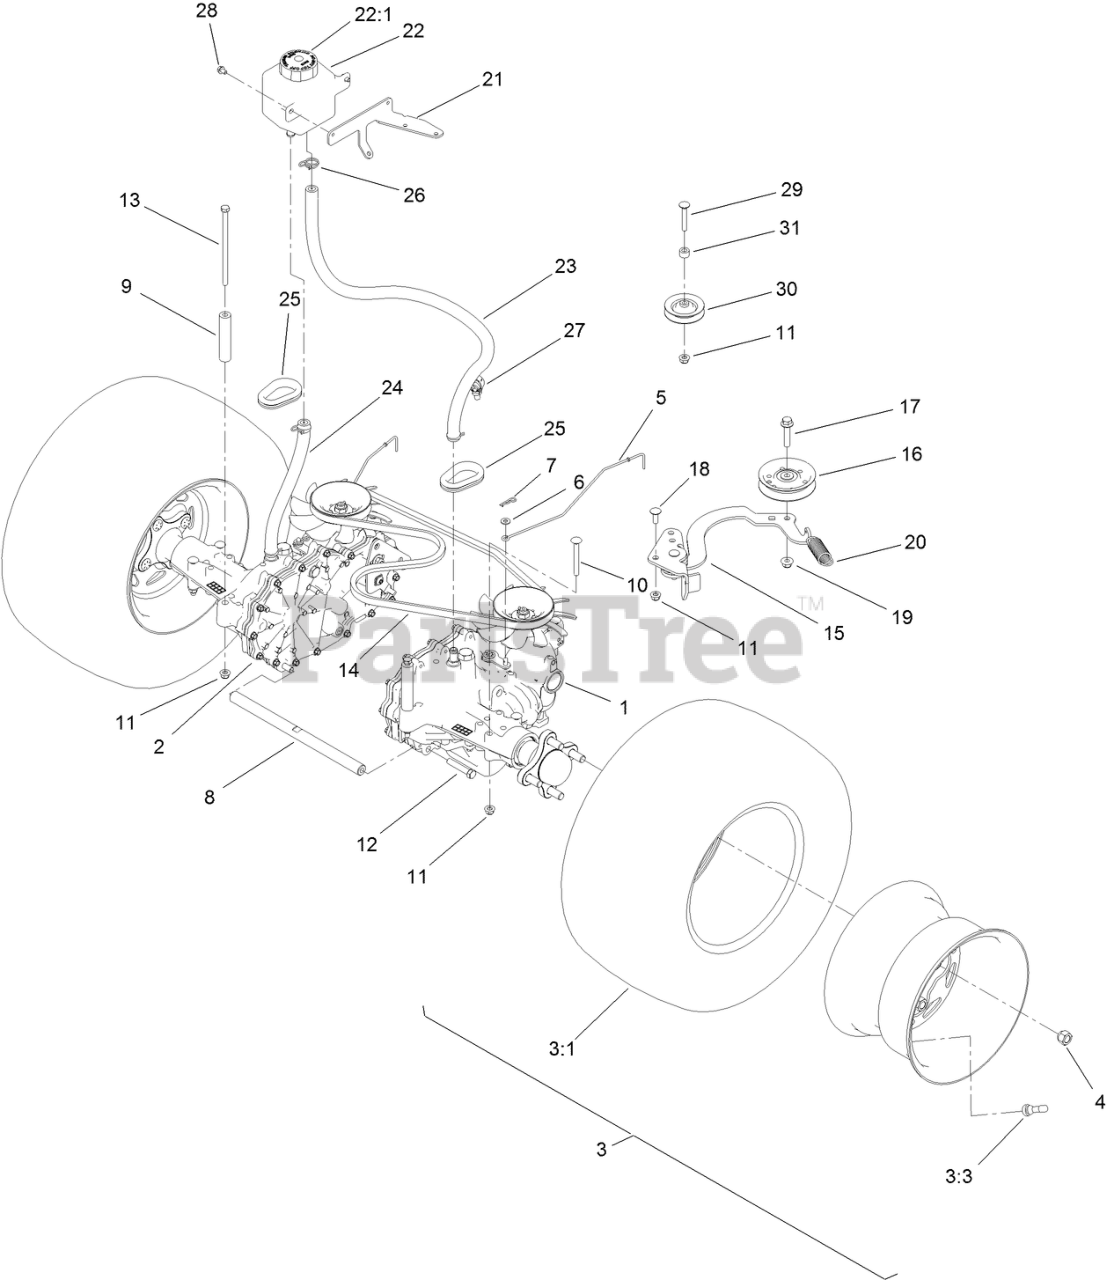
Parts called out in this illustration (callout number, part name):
1	TRANSMISSION, ZT-2800 LH
2	TRANSMISSION, ZT-2800 RH
3	TIRE ASM
4	NUT-LUG
5	ROD-BYPASS
6	WASHER-FLAT
7	PIN-COTTER
8	SHAFT-CROSS, HYDRO
9	SPACER - TRANSMISSION
10	SCREW-CARR
11	NUT-HF, NI
12	SCREW-HH W/LOCTITE
13	SCREW-HH
14	BELT-V
15	IDLER ARM ASM
16	PULLEY-IDLER, FLAT
17	SCREW-HHF
18	BOLT-CARR
19	NUT-HF, NI
20	SPRING-EXTENSION
21	BRACKET - EXPANSION TANK
22	TANK-HYD
22:1	CAP-RESERVOIR, HYD
23	HOSE-HYDRO
24	HOSE-OVERFLOW
25	GROMMET
26	CLAMP-HOSE
27	CLIP-TIE
28	SCREW-HWH
29	BOLT-CARR
30	PULLEY-IDLER
31	SPACER
